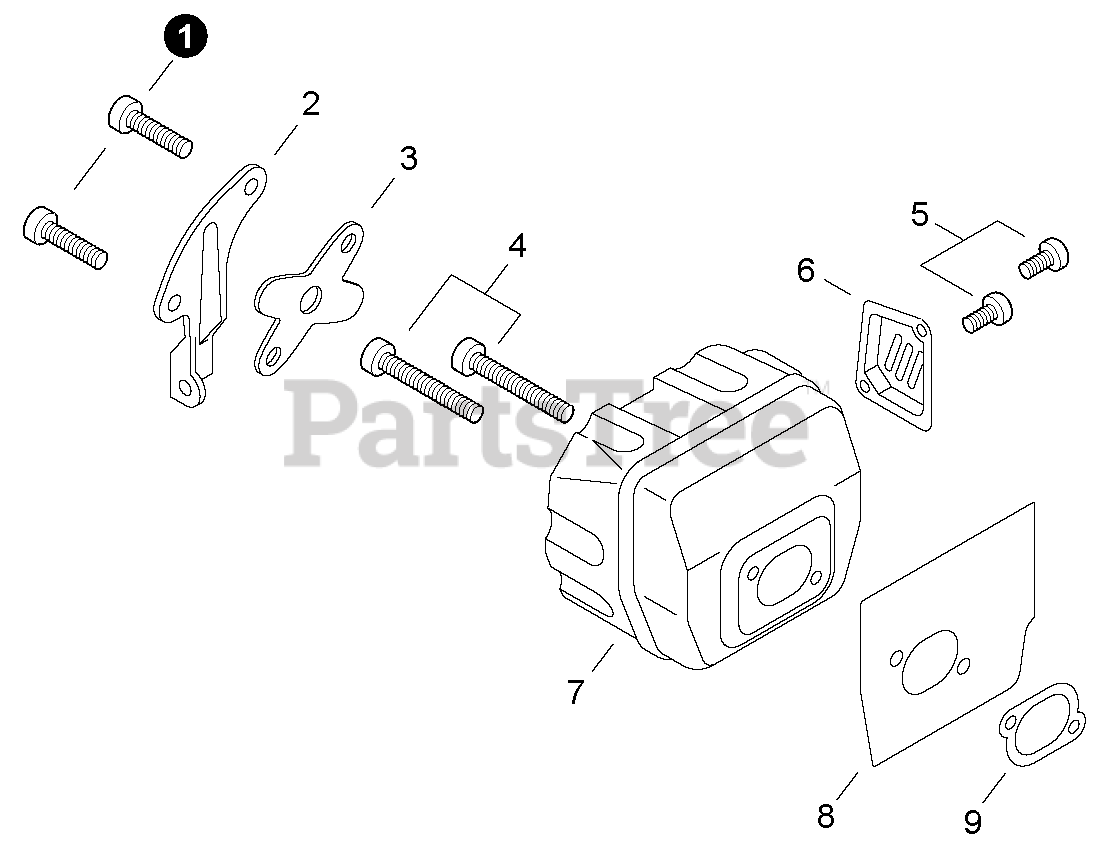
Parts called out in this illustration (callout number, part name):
1	BOLT 5×12
2	BRACKET, MUFFLER
3	COVER, MUFFLER
4	BOLT 5×20
5	BOLT 4×10
6	OUTLET, EXHAUST
7	MUFFLER
8	HEAT SHIELD, EXHAUST
9	GASKET, EXHAUST
